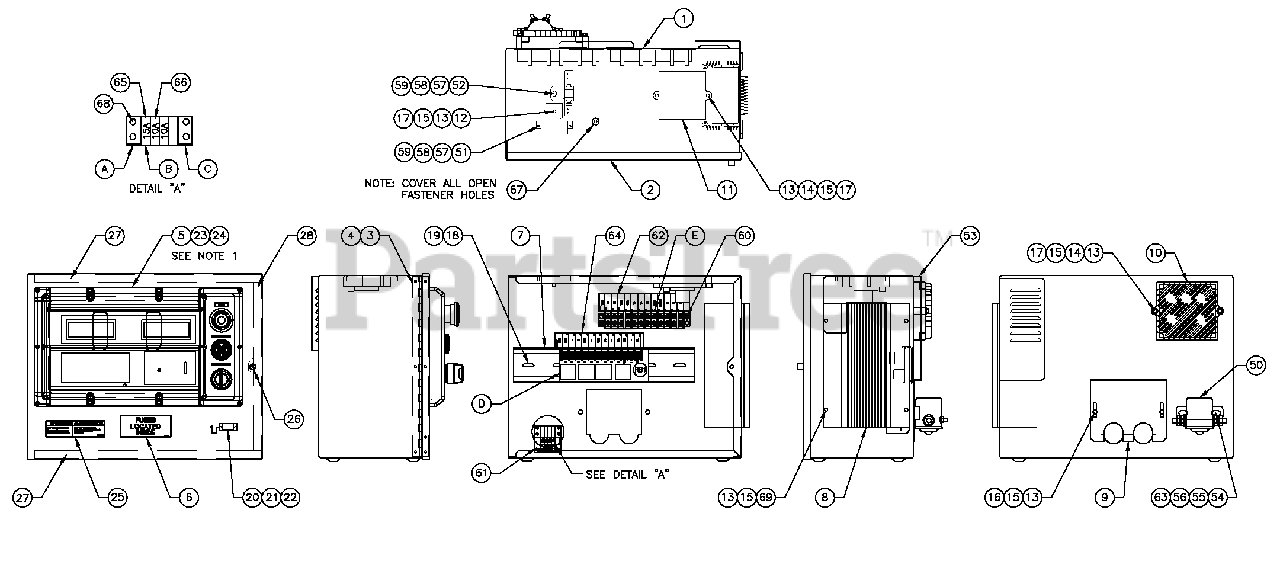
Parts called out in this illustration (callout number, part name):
1	ENCL H/G CONTROL PANEL
2	COVER CONTROL PANEL
3	HINGE CONTINUOUS H PANEL
4	RIVET POP .125X.275SS
5	ASSY PROGRAMMED H-100
6	DECAL FUSES LOCATED INSIDE
7	RAIL SNAPTRACK PCB HOLDER BULK (12"LG)
8	ASSY PCB 10A UL BATT CHRGR12V
9	PLATE HARNESS CLAMP
10	ASSY PCB PWRAVRW/AMP HEADER
11	ASSY PCB BOSCH GOV DRIVER
12	DIO BRIDGE 25A 600V
13	WASHER LOCK M5
14	SCREW PPHM M5-0.8X 30 SS
15	WASHER FLAT M5
16	SCREW HHPM M5-0.8X 12
17	NUT HEX M5-0.8 G8 YEL CHR
18	WASHER FLAT M4
19	SCREW PHTT M4-0.7X 10 ZYC
20	CONN DUST CAP W/CHAIN DB9
21	WASHER FLAT M3.5
22	SCREW PHTT M3.5-0.6 X 10
23	SCREW PPHM M4-0.7 X 8 BLX OX
24	WASHER LOCK #8-M4
25	DECAL WRN BATT CHRG12/24V BI
26	M5-0.8 CAPTIVE PANEL KNLD HD
27	SEAL COVER 3.18 X 12.7 X 382
28	SEAL COVER 3.18 X 12.7 X 283
50	RELAY CONTACTOR 12VDC
53	COVER CONTROL PANEL SIDE
54	SCREW HHC 1/4-20 X 3/4 G5
55	WASHER FLAT M6-1/4
56	WASHER LOCK M6-1/4
57	WASHER LOCK M3
58	NUT HEX M3-0.5 G8 YEL CHR
59	WASHER FLAT M3
60	SCREW PHTT #6-32 X 5/8 ZYC
61	DECAL CPL CONTROL PANEL FUSES
62	DECAL CPL 5.4/6.8LTB3
63	NUT HEX 1/4-20 STEEL
64	DECAL CPL 5.4/6.8L RELAY BOARD
65	FUSE ATO TYPE 15 AMP (BLUE)
66	FUSE ATO TYPE 10 AMP (RED)
67	SEAL WEATHER .45"DIA
68	SCREW PHTT #6-32 X 3/8 ZYC
69	SCREW PHTT M5-0.8X 16 ZYC
A	ADPTRRH SIDE WICKMANN 178.6191
B	HOLDER FUSE WICKMANN 178.6150
C	ADPTRLH SIDE WICKMANN 178.6192
D	ASSY PCB G-PANEL RELAY 12VDC
E	BLOCK TERM 20A12 X6X1100V
